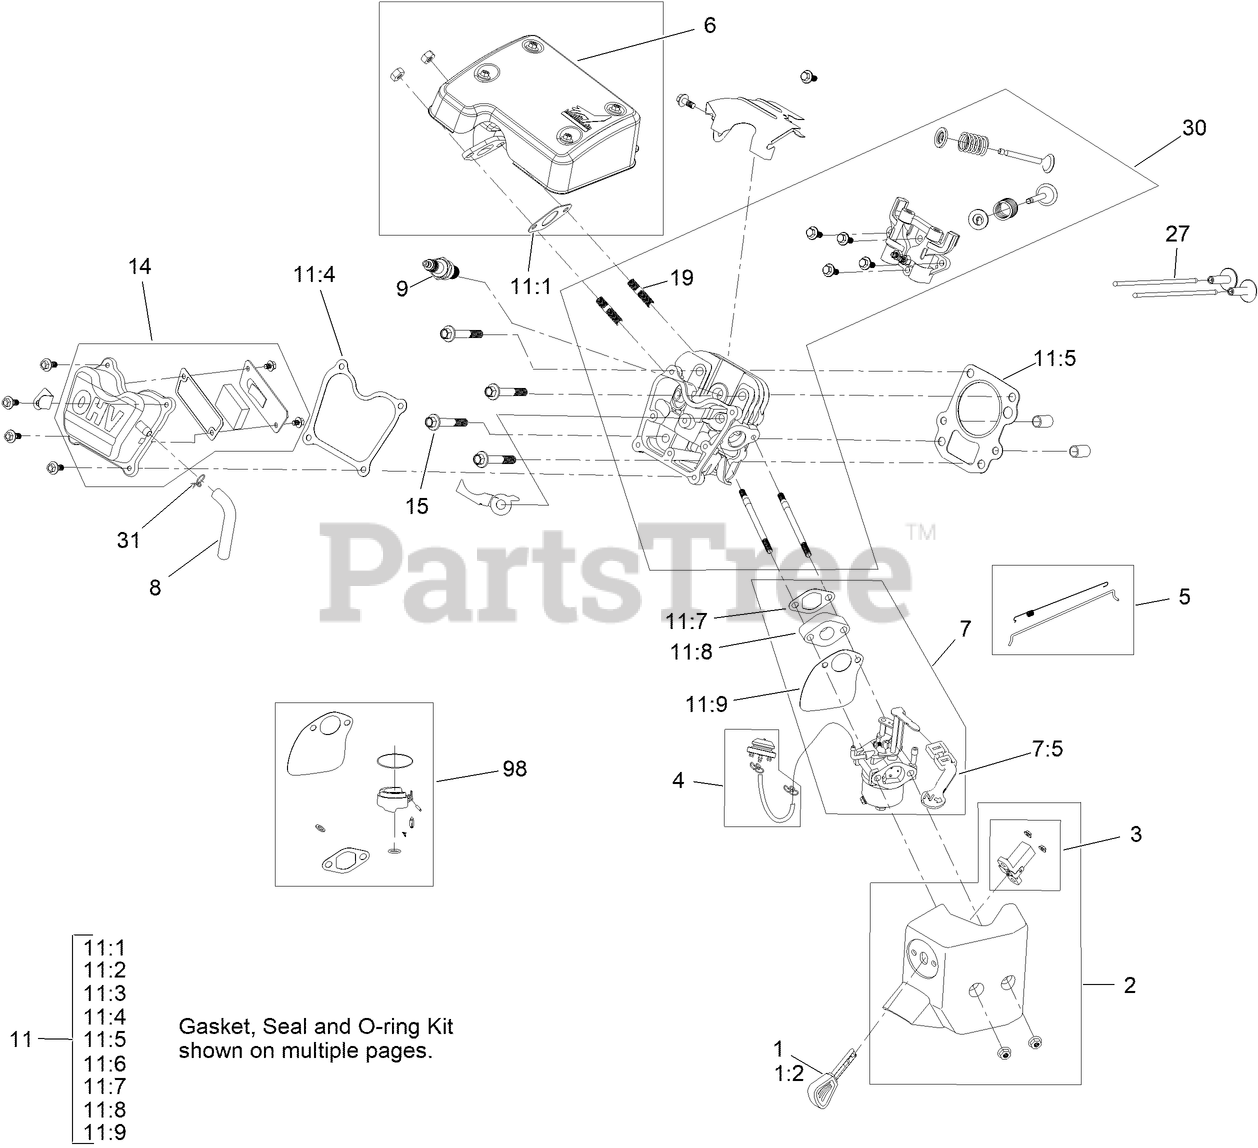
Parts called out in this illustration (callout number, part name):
1	KEY AND LANYARD KIT
2	HEATER BOX KIT
3	SWITCH KIT
4	PRIMER BULB KIT
5	GOVERNOR KIT
6	MUFFLER KIT
7	COMPLETE CARB SERVICE KIT
7:5	LEVER-CHOKE
8	TUBE-BREATHER
9	SPARK PLUG
11	GASKET, SEAL, AND O-RING KIT
11:1	GASKET-EXHAUST
11:2	SEAL-OIL
11:3	SEAL-OIL
11:4	GASKET-COVER, VALVE
11:5	GASKET-HEAD, CYLINDER
11:6	GASKET-COVER, CRANKCASE
11:7	GASKET-INSULATOR
11:8	INSULATOR-CARBURETOR
11:9	GASKET-CARBURETOR
14	VALVE COVER ASM
15	SCREW-HHF
19	STUD-EXHAUST
27	ROD-PUSH
30	COMPLETE HEAD ASM
31	CLAMP-HOSE
98	CARBURETOR REPAIR KIT
